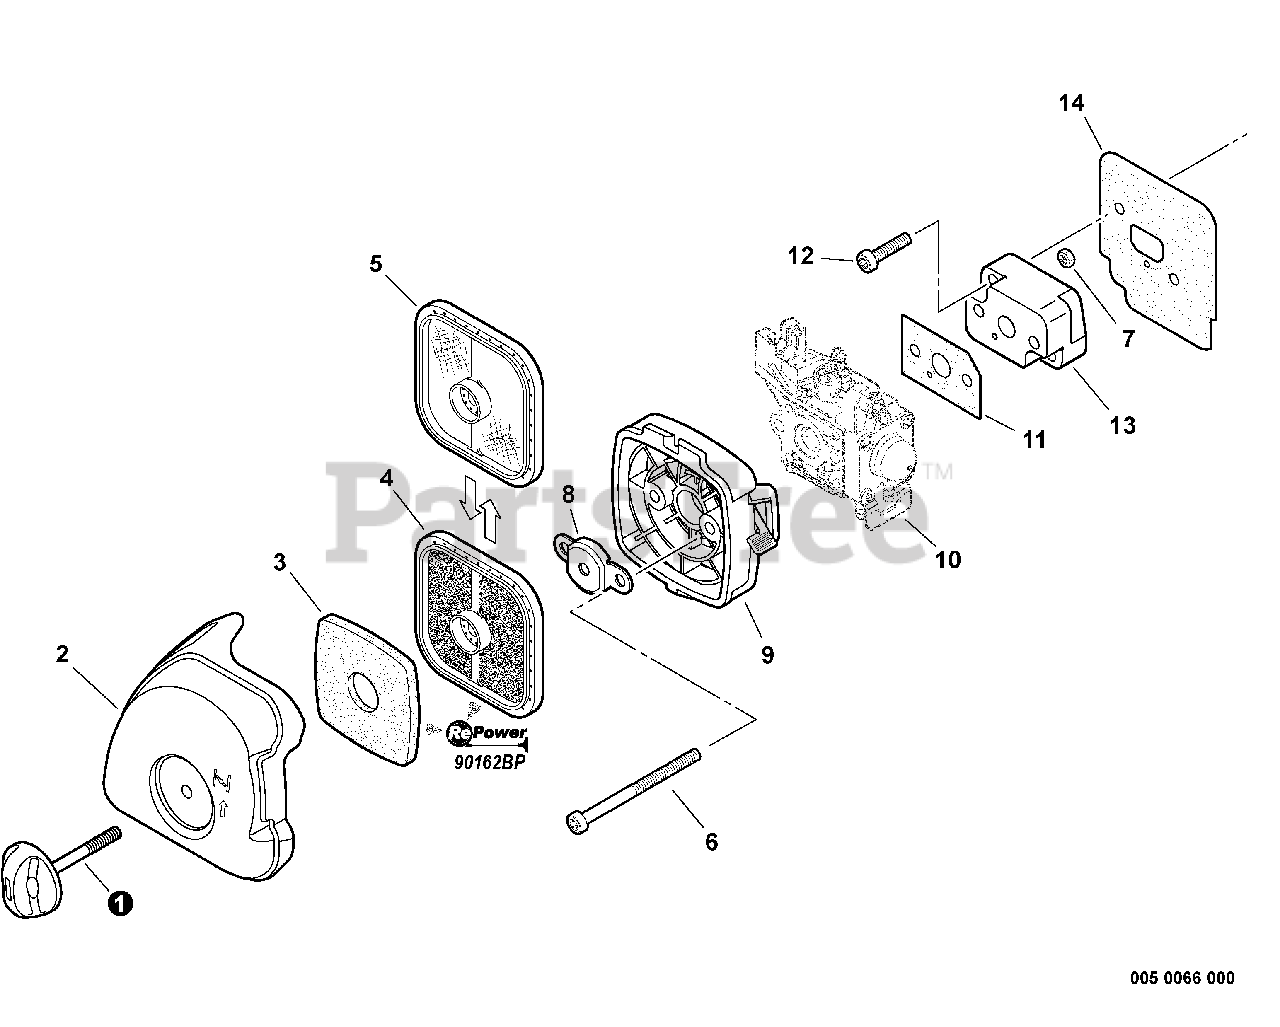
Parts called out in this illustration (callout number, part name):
1	THUMBSCREW
2	COVER, AIR FILTER
3	PRE-FILTER -- FOAM
4	FILTER, AIR - DOUBLE LAYER
5	FILTER, AIR - SINGLE LAYER
6	SCREW - 5X65
8	PLATE, PREVENT
9	CASE, AIR FILTER
10	CARBURETOR
11	GASKET, INTAKE
12	SCREW - 5X20
13	INSULATOR, INTAKE
14	SHIELD, INTAKE
15	RePower TUNE-UP KIT
